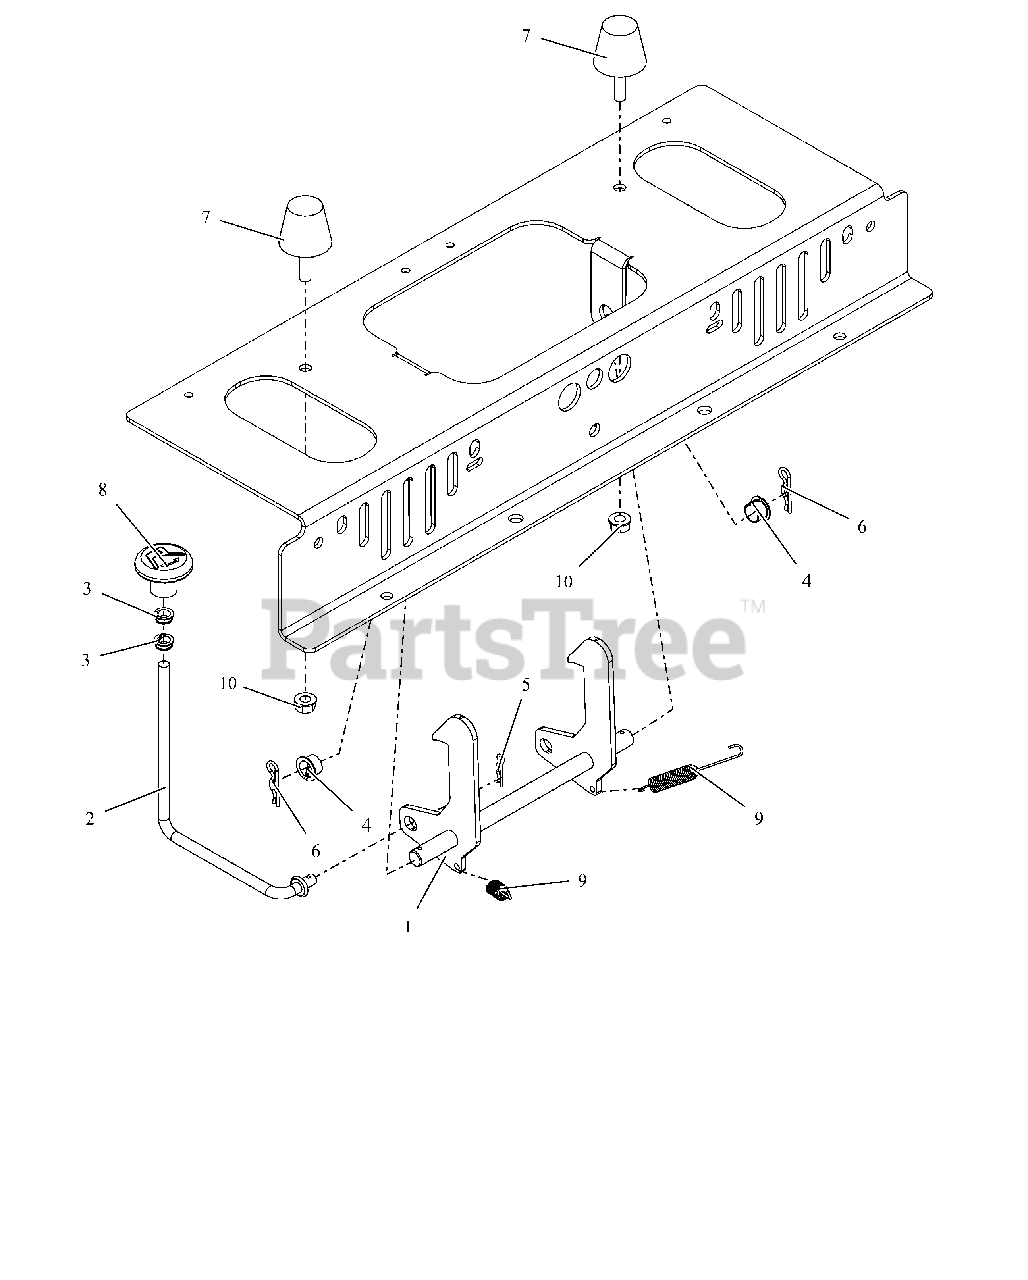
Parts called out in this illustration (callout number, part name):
1	SEAT LATCH WLDMT - LOW FILM
2	LINKAGE, SEAT RELEASE
3	BUSHING, POLYLINER-.38 SNAPIN
4	BUSHING, POLYLINER-.50 SPLIT
5	PIN, HAIR #225 .072X1.09
6	PIN, HAIR-INT .08X.38X1.42 ZCC
7	BUMPER,STUD MOUNTED CONE SHAPE
8	KNOB, PUSH/PULL
9	SG-TENS .043X.44X3.31 WLD 5.8
10	NUT,SPNLK-FLG .31-18 G5 ZCC
